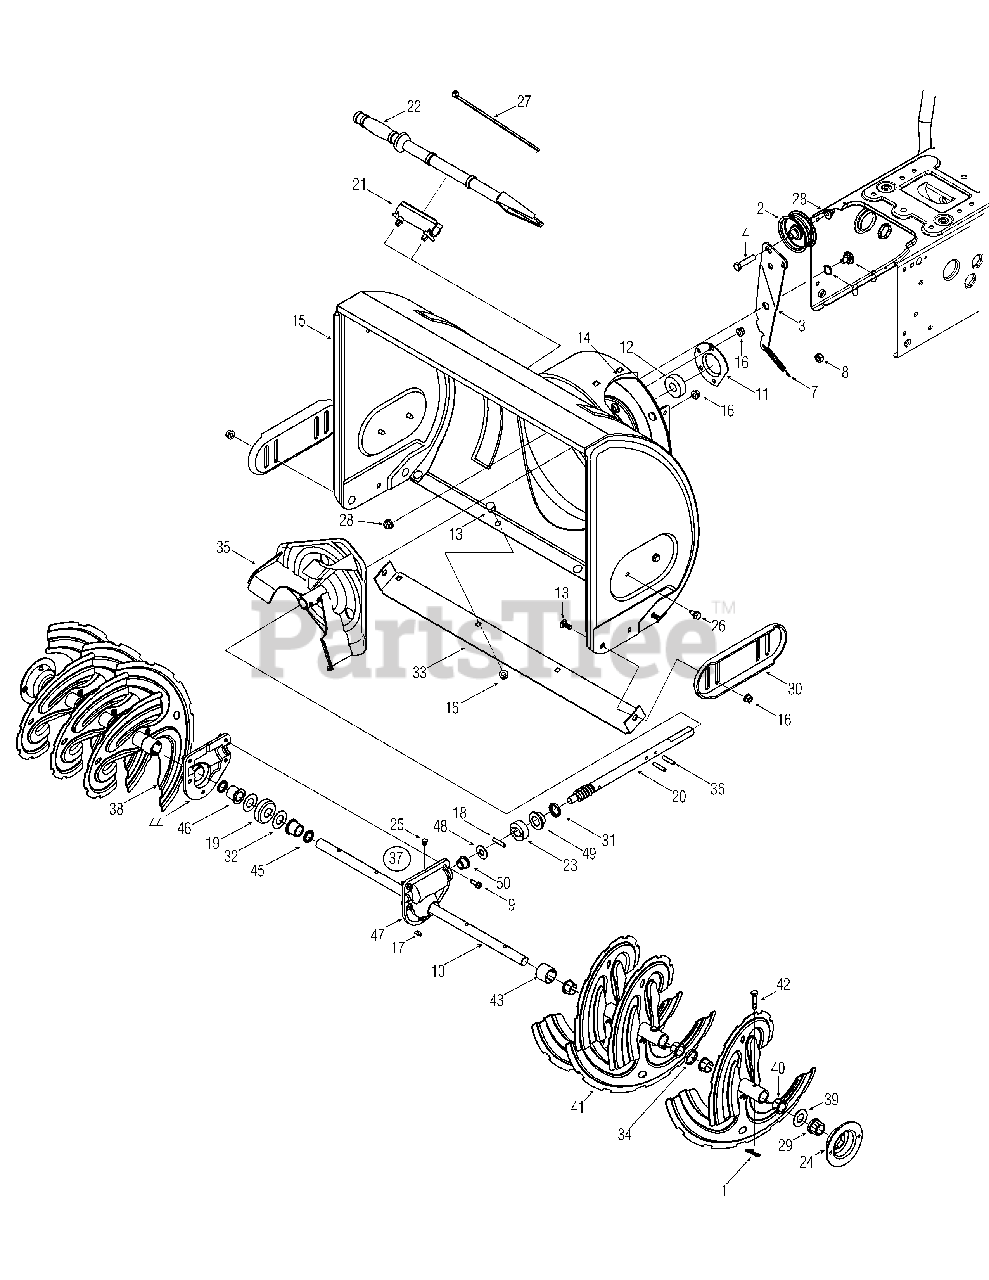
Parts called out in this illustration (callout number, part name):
1	Cotter Pin
2	Flat Idler
4	Hex Cap Screw 3/8-16 x 1.75
5	Shoulder Screw
6	Wave Washer
7	Extension Spring
8	Hex Nut 5/16-18
9	Self Tapping Screw, 1/4-20 x.75
10	Auger Axle, 30"
12	Ball Bearing
13	Carriage Bolt, 5/16-18 x.75
17	Hi-Pro Key, 3/16 x 5/8
19	Worm Gear, 20-tooth
20	Worm Shaft
21	Clean-Out Tool Mount
22	Clean-Out Tool
23	Thrust Collar
25	Grease Plug
26	Hex Screw, 5/16-18 x.625
27	Cable Tie
28	Flange Lock Nut 3/8-16
29	Hex Flange Bearing
31	Grease Seal
32	Flat Washer, .76 x 1.5 x.030
33	Shave Plate, 30"
34	Spacer, 1.25OD x.75ID x 3/16 Lg.
37	Gearbox Assembly Complete, 30"
39	Flat Washer
40	Flange Bushing
42	Shear Pin,.25 x 1.50
43	Spacer, 1.25OD x.75ID x 1.00 Lg.
44	RH Housing (Incl ref. 45 & 46)
46	Flange Bearing - RH Housing
47	LH Housing (Incl ref. 45 & 46)
48	Flat Washer,.51 x 1.12 x.06
49	Flange Bearing,.75 x 1.0 x.59
50	Flange Bearing,.503 ID x.75 OD
